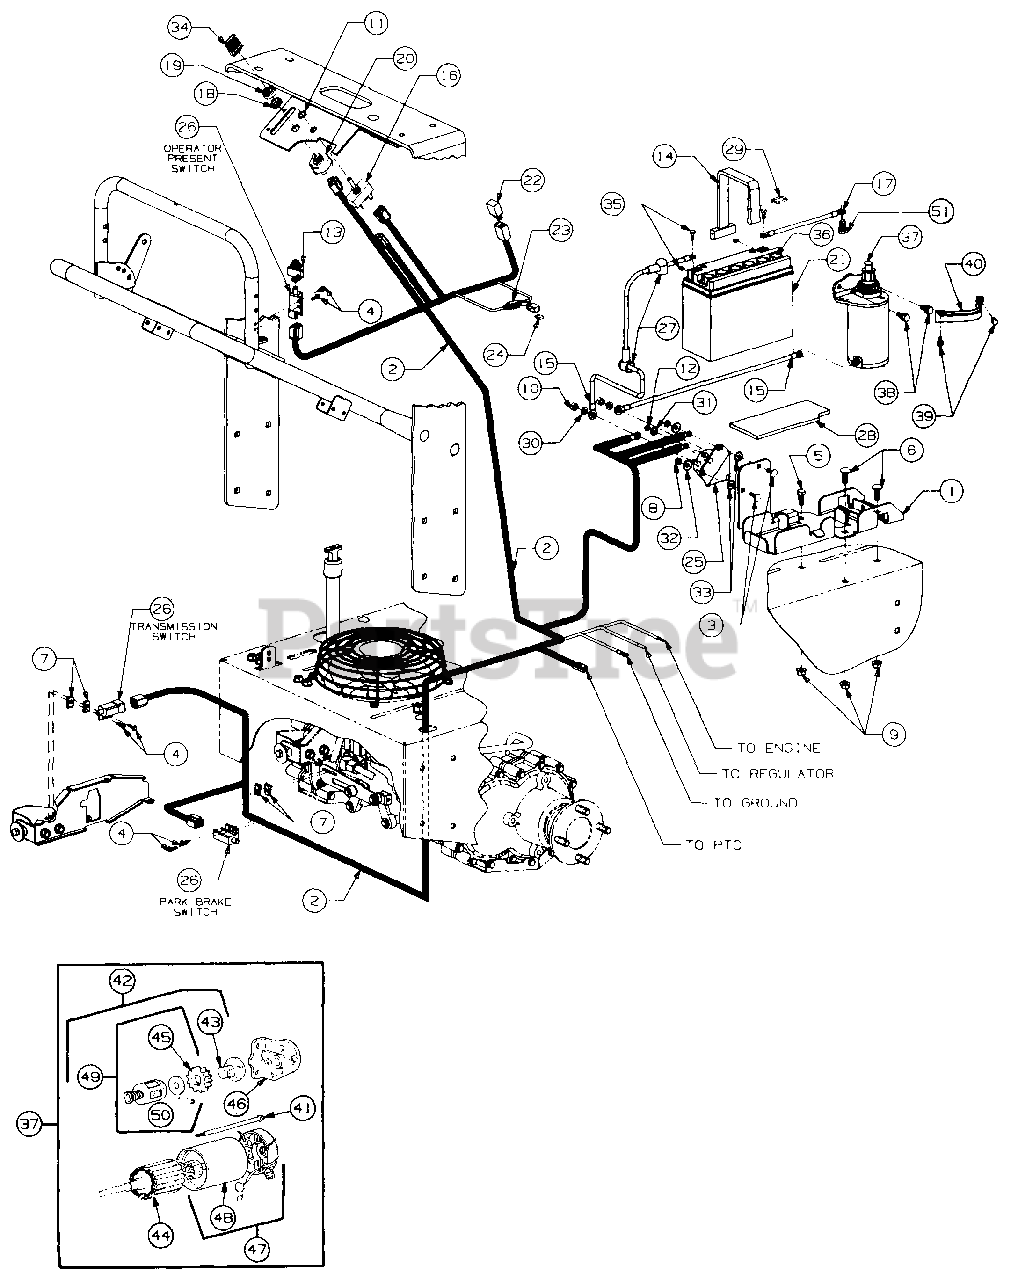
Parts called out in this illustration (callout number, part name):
1	Bracket, Battery
2	Harness, Electric Start
3	Bolt, Carriage, 1/4-20 X .62 Lg
4	Screw, Hex Wash Hd Tapp, #10-24 X .62 Lg
5	Screw, Hex Cap, 3/8-16 X .88 Lg GR5
6	Bolt, Carriage, 3/8-16 X 1.0 Lg GR5
7	Nut, Speed
8	Nut, Hex Center Lock, 1/4-20
9	Nut, Hex Flanged, 3/8-16
10	Nut, Hex, 5/16-18 GR5
11	Nut, Hex, 1/2-27 X .100 Thk
12	Nut, Hex Sems, #10-32
13	Cover, Protective
14	Strap, Battery Retainer
15	Wire, Insulated, 6 ga. Red
16	Switch, PTO
17	Wire, Insulated, 6 ga. Black
18	Nut, Ignition Switch
19	Cap, Ignition Switch
20	Switch, Ignition
21	Battery
22	Relay
23	Holder, Inline Fuse
24	Fuse, 20 Amp Mini
25	Solenoid
26	Switch Double Poled Plunger
27	Cover, Terminal Red
28	Tray, Protective Battery
29	Hook, Wire Rectangular
30	Washer, Lock, 5/16
31	Washer, External Lock, 3/8
32	Washer, Bell, .265 X .75 X .062 Thk
33	Washer Int-Ext Lock 1/4
34	Key, Ignition (Set of 2)
35	Bolt, Battery (Set of 2)
36	Cap, Battery
37	Starter
38	Screw, Mounting
39	Screw, Sem
40	Shield, Starter Drive
41	Bolt, Thru
42	Kit, Bendix Drive
43	Drive, Starter
44	Armature Assy
45	Gear
47	Cap Assy, Commutator End
48	Housing Assy
49	Kit, Spring
50	Pin, Roll
